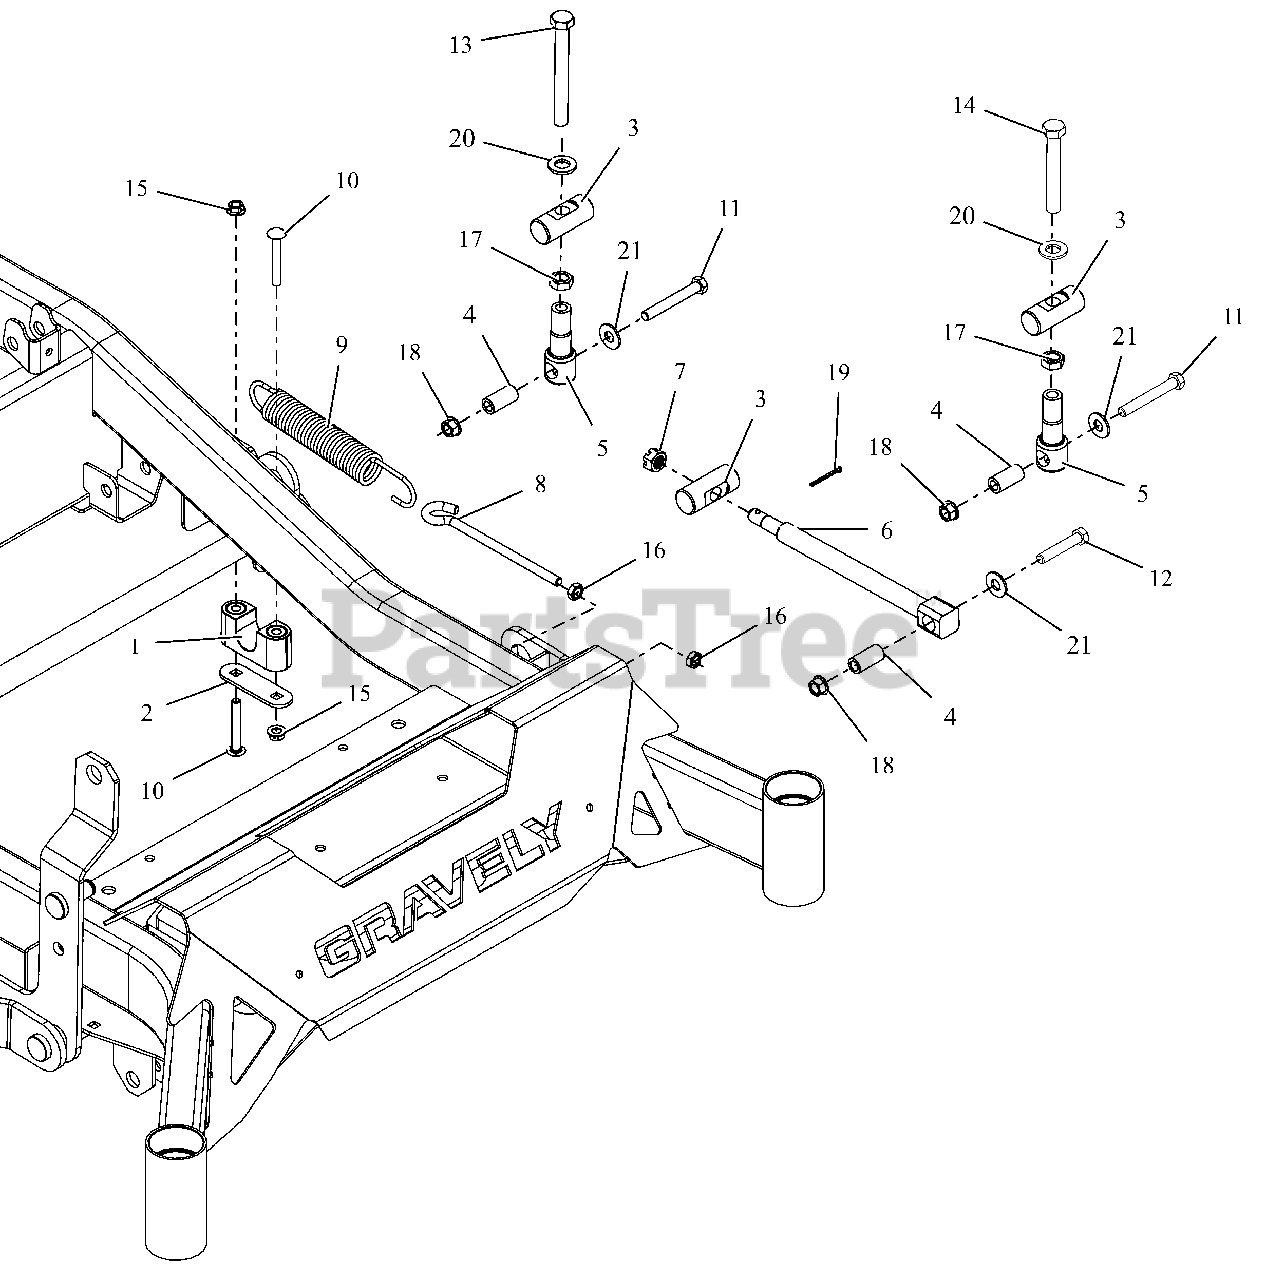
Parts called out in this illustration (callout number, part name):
1	ASM-BUSHING, DECK LIFT
2	PLATE, BEARING SUPPORT
3	PIN, DECK LIFT
4	SPACER, DECK LEVELING
5	LINK, DECK LIFT FORMED
6	DRAG,LINK-HD
7	NUT-SL .50-13
8	BOLT,.38-16 X 5.25-.62 DIA EYE
9	SG-TENS .162X1.25X8.25 WLD 25
10	BLT-RDHDSQSHNK .31-18X2.25 YWZ
11	BLT-HEX .38-16X2.75 GR8 YWZC
12	@BLT-HEX .38-16X2.00 GR5 YWZC
13	@BLT-HEX .5-13-4.5GR8 FULL THD
14	BLT-HEX .50-13X3.50 GR5 FTH
15	@NUT-LK-CTR-FLG .31-18 YZ GR F
16	NUT-HEX-JAM .375-16 YWZC
17	NUT-JAM .50-13 YWZC
18	@NUT-LK-TOP-FLG .38-16 YWZC
19	@PIN-CTR .12X1.25 EXTPRSQCT YZ
20	FLATWASHER 1/2 SAE HARD 15906
21	@WSHR-FL-STL.438X1.00X.083 YWZ
